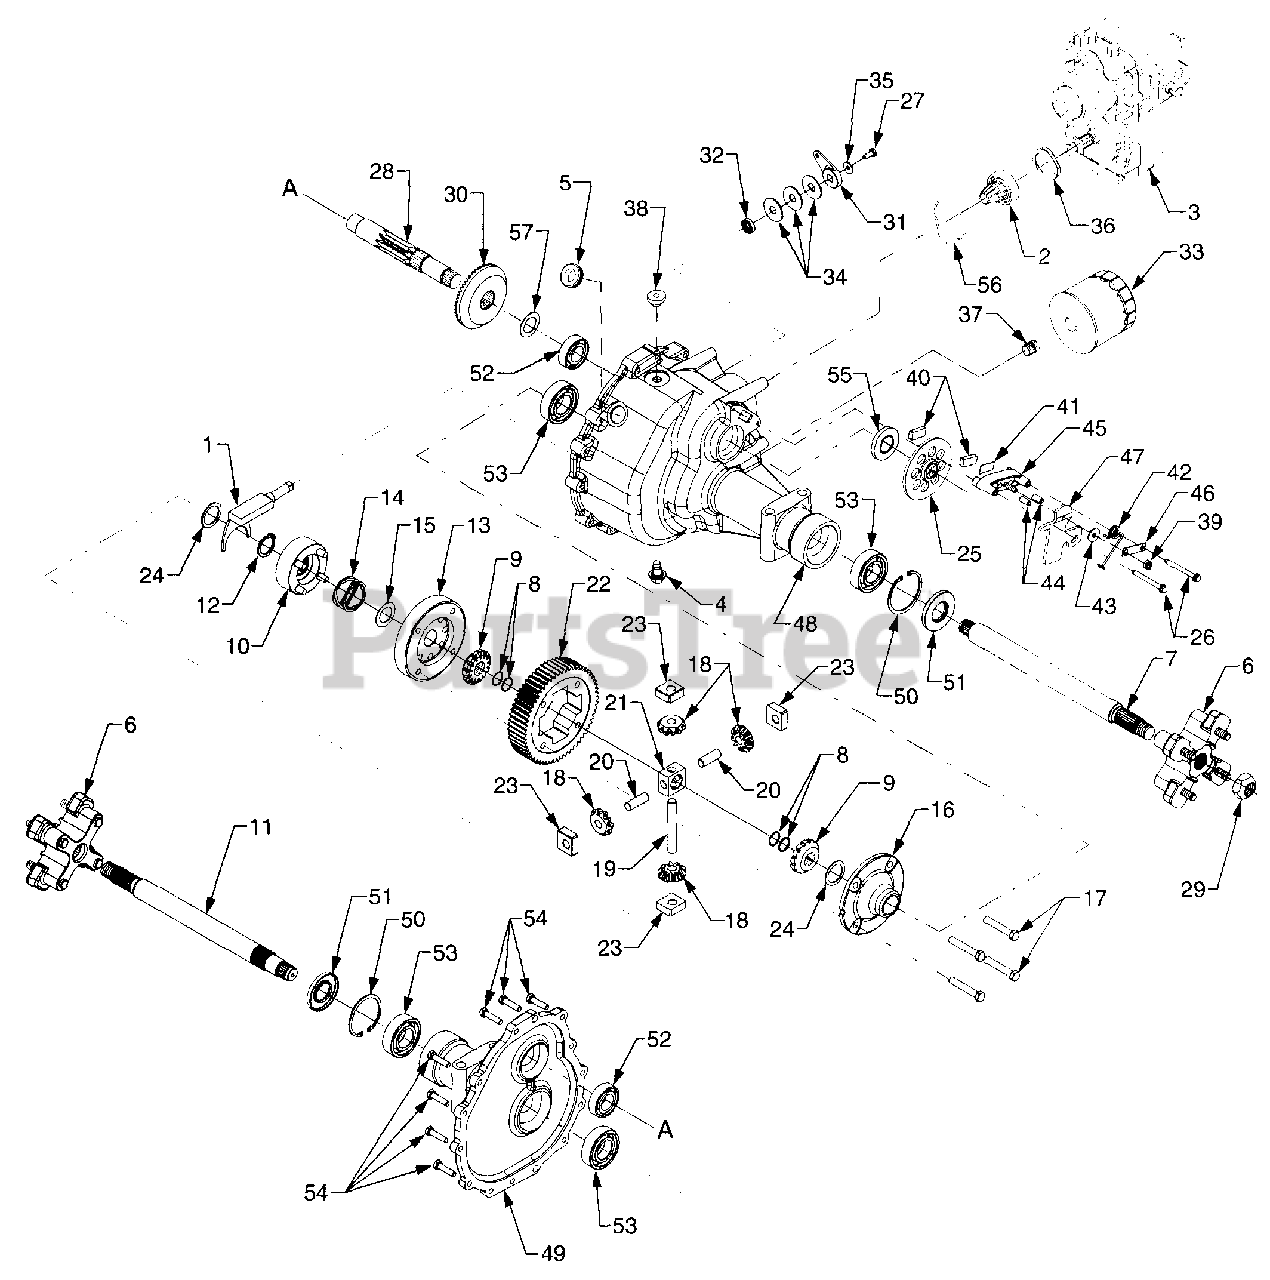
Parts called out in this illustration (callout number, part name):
1	Shaft, Differential Actuator
2	Gear Assembly, Pinion 13T
3	Hydrostatic Transmission Assy.
4	Plug, Drain, M14 x 1.5 x .827
5	Grommet, Rubber
6	Hub Assembly, Wheel
7	Axle Shaft, 15.08 Long - RH
8	Retaining Ring
9	Gear, Spur, 14T
10	Collar Assembly, Diff. Lock
11	Axle Shaft, 15.08 Long - LH
12	Retaining Ring
13	Housing, Diff. Lock
14	Spring, Compression
15	Washer, Thrust, 1.007 x 1.542 x .03
16	Housing, Diff. Cover
17	Hex Cap Screw, 3/8-24 x 2.25 GR8
18	Gear, Differential 10T
19	Shaft, Cross, .5 x 3.485
20	Shaft, Cross,
21	Differential Pinion Block
22	Gear, Spur 60T
23	Block, Thrust Miter
24	Washer, Flat, 1.187 x 1.56 x .062
25	Disc, Brake
26	Screw, Hex Wash. Hd. Tapp 1/4-20 x 2.375
27	Hex Cap Screw, 1/4-20 x .62 GR5
28	Shaft, Output 9T
29	Nut, Lock, 7/8-14
30	Gear, Bevel 54T
31	Arm, Diff. Lock Actuator
32	Seal, Oil
33	Filter, Oil
34	Washer, Flat, .51 x 1.5 x .07
35	Washer, Belleville, .265 x .75 x .062
36	Washer, Spring
37	Fitting, Filter Nipple
39	Nut, Hex Insert Lock, 5/16-24
40	Pad, Brake
41	Plate, Puck
42	Spring, Torsion
43	Washer, Flat, .343 x .88 x .062
44	Pin, Brake Actuator
45	Yoke, Brake
46	Bracket, Brake Anti-Rotation
47	Arm, Brake Actuator
48	Housing, RH
49	Housing LH
50	Retaining Ring
51	Seal, Oil
52	Bearing, Ball
53	Bearing, Ball
54	Screw, Hex Cap Locking 5/16-18 x 1.25 GR5
55	Seal, Oil 1.0 ID
56	Seal, Gland O-Ring
57	Washer, Flat, 1.0 x 1.56 x .030
